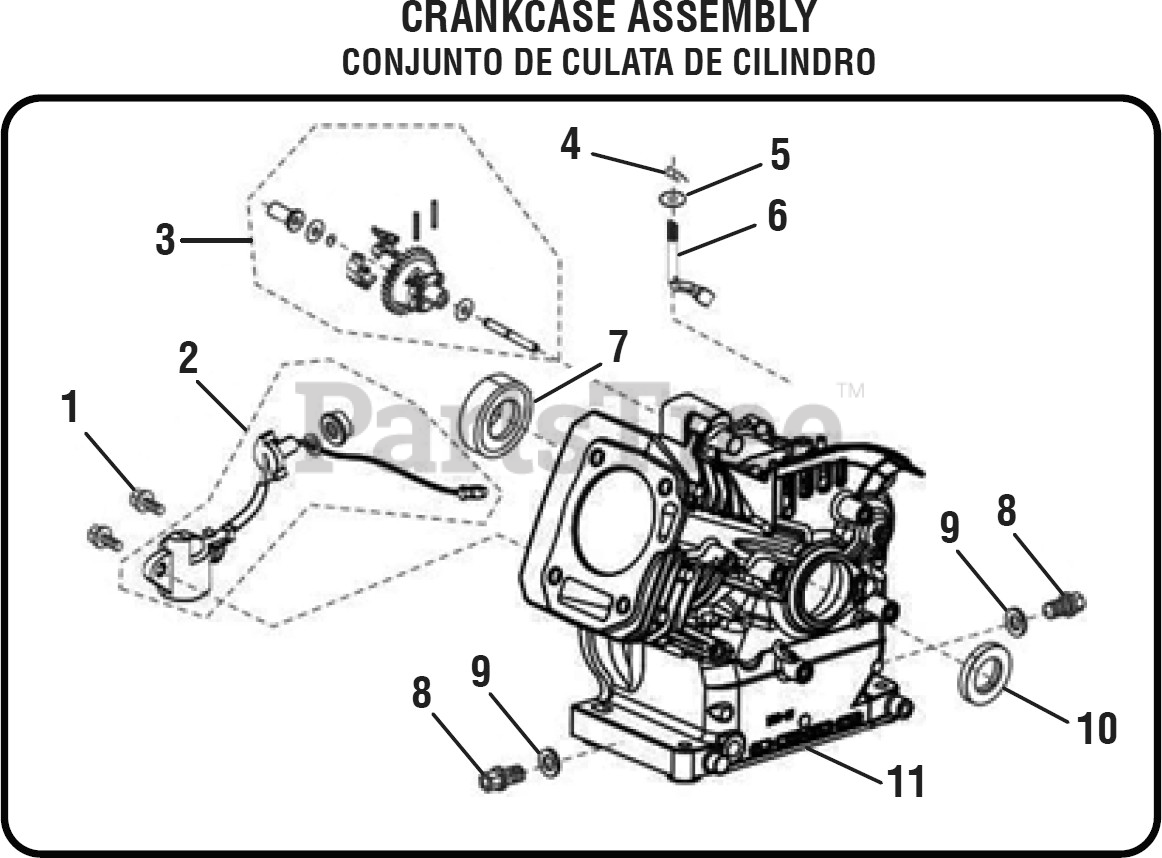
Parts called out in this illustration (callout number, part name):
2	Engine Oil Sensor
3	Governor Gear Assembly
4	Pin
5	Washer
6	Governor Arm
7	Ball Bearing
8	Drain Plug
9	Washer
10	Oil Seal
11	Crankcase Assembly
